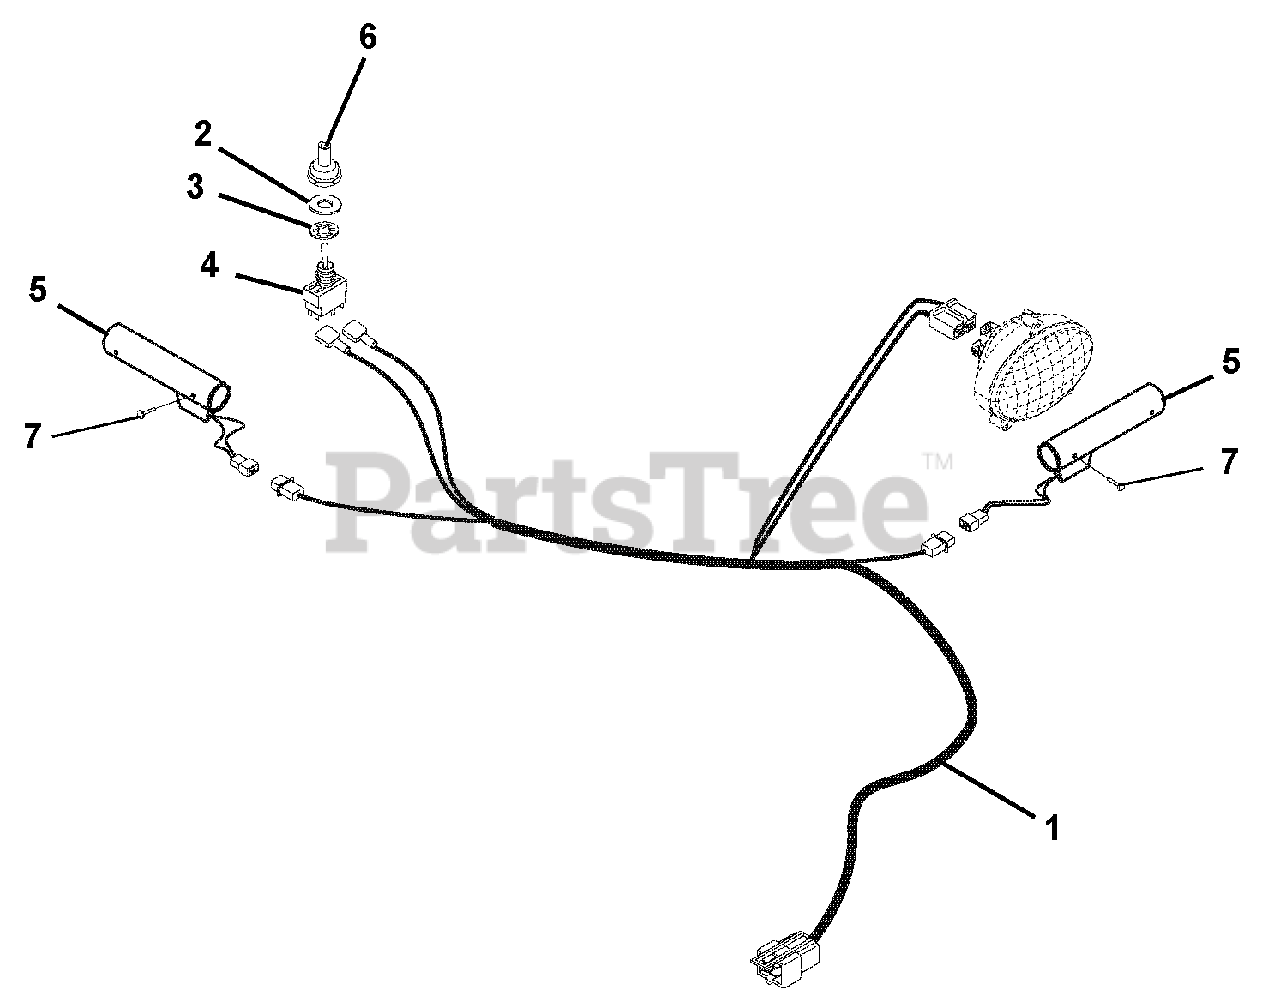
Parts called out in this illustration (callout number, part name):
1	Harness, Wiring-Light and Handwarmer
2	Washer, Flat Steel .51 x .88 x .024
3	Washer, Locking Internal .56 x .04
4	Switch, On/Off Hand Warmer
5	Hand Warmer with Terminal
6	Boot, Switch
7	Rivet, Pop #43 .125 x .313
